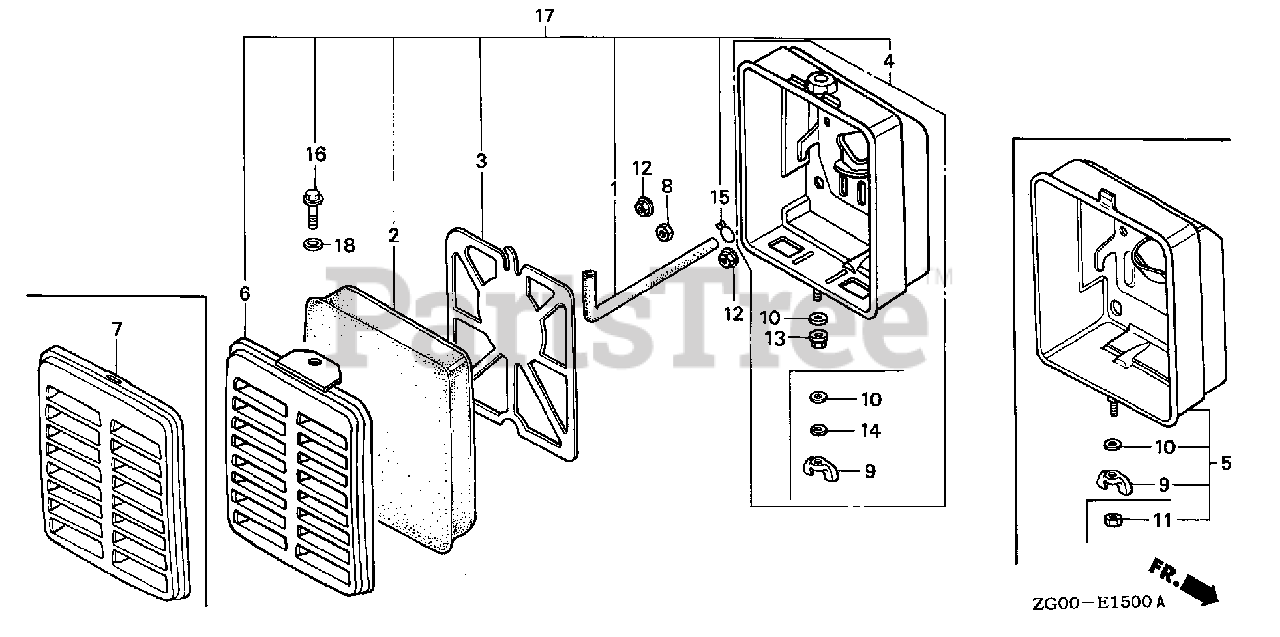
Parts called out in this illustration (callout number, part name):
1	TUBE, BREATHER
2	ELEMENT, AIR CLEANER
3	GRID, AIR CLEANER
5	HOUSING, AIR CLEANER
7	COVER, AIR CLEANER
9	WINGNUT, TOOL BOX SETTING
10	WASHER, PLAIN (6MM)
12	NUT, FLANGE (5MM)
